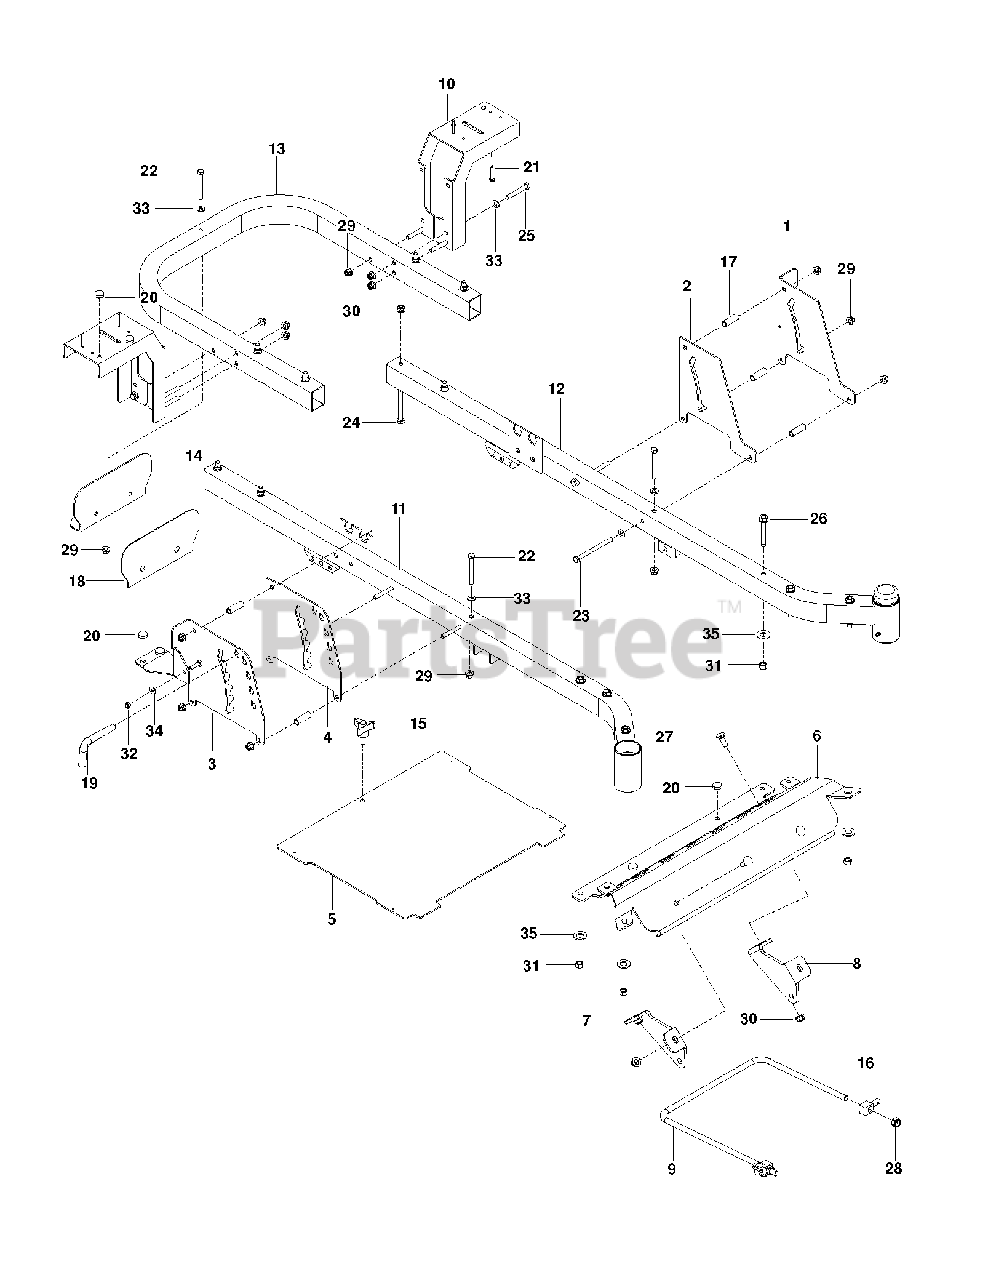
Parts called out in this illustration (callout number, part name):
1	PLATE, OUTER BRAKE, BLACK
2	PLATE, BRAKE LATCH, BLACK
4	PLATE, DECK HEIGHT, BLACK
5	PLATE, FOOT W/DECALS SPZ
6	FOOT REST, MED BLUE
7	MOUNT, STRUT, RT, BLK
8	MOUNT, STRUT, LT, BLK
9	LINK, FRONT SUSP.
10	SUPPORT, FENDER, BLACK
11	FRAME, RT, BLUE
12	FRAME, LT, BLUE
13	FRAME TUBE, REAR, BLUE
14	PLATE, HITCH BLU
15	KNOB W/STUD
17	SPACER, .334 ID X .5 OD X 1.5
20	GROMMET, BUMPER
21	SCR #10-12X1-1/2HEX WASH HD ZD
27	RHSNB 3/8C X 1
28	7/16-14 HEX NUT W/NYL RING ZD
29	5/16-18 NYLOC FLANGE NUT
30	NUT 3/8-16 HEX FLG NYLOC ZD
31	NUT HEX 3/8-16 NYLON, THIN
32	LOCKNUT
